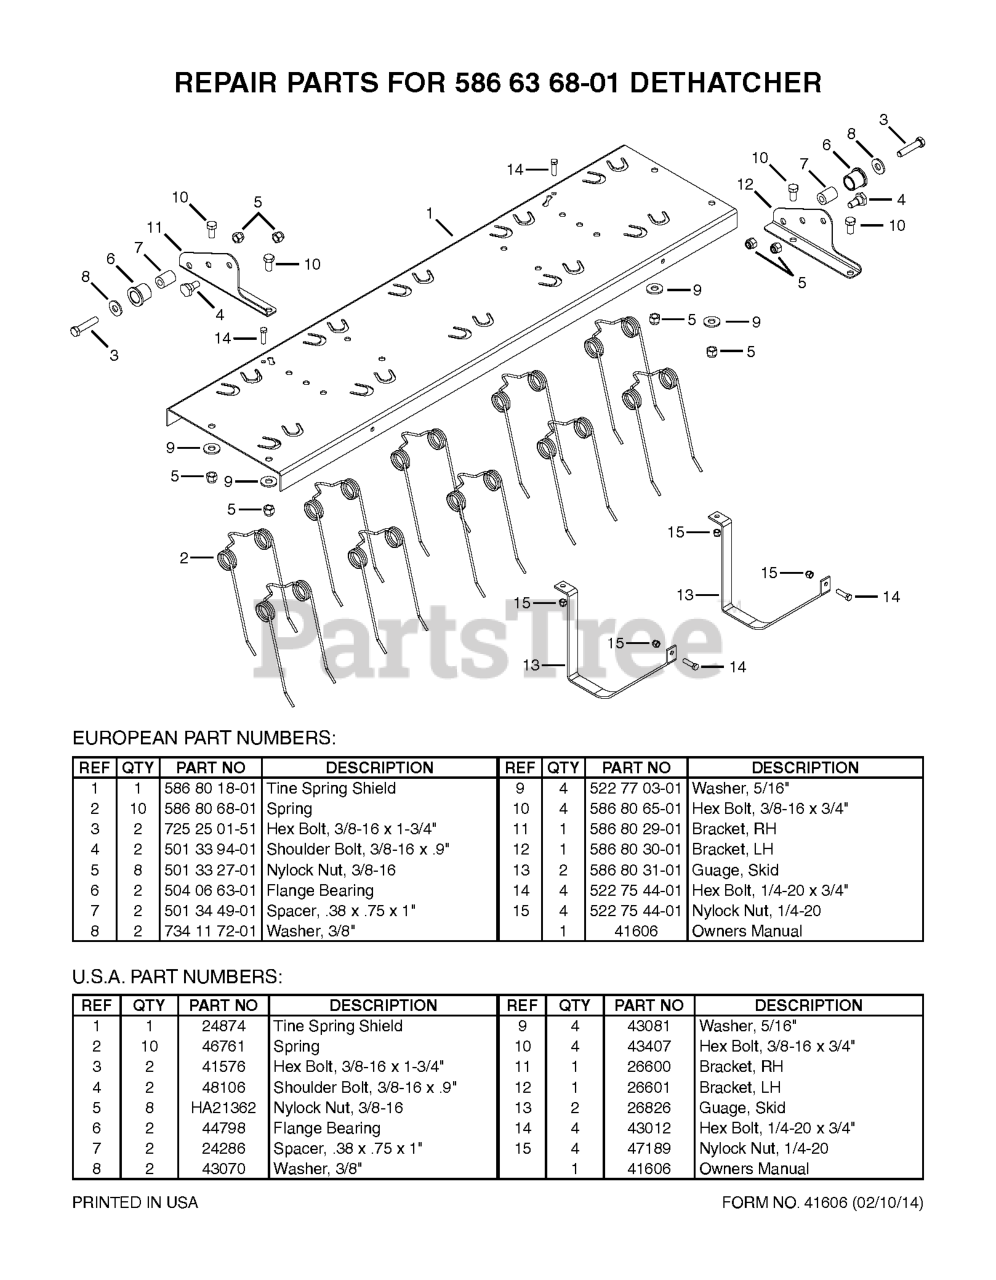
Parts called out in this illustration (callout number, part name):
4	BOLT 48106
7	SPACER 24286
8	WASHER
